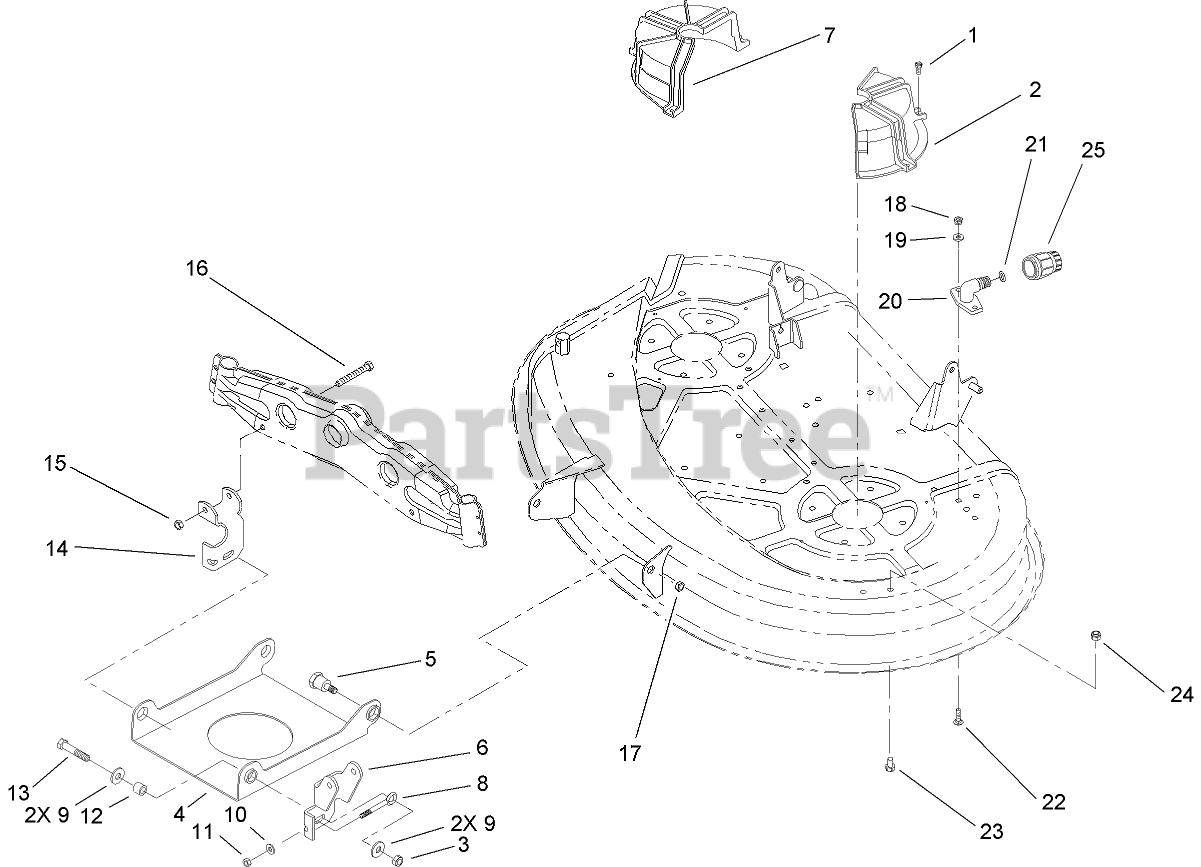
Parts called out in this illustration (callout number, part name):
1	SCREW-HWHTF
2	GUIDE-BELT, LH
3	NUT-LOCK, NI
4	PAN-DECK SUSPENSION, FRONT
5	BOLT-SHOULDER, HH
6	BRACKET-SUSPENSION, LH
7	GUIDE-BELT, RH
8	SCREW-ADJUSTING
9	WASHER-HARDENED
10	WASHER-FLAT
11	NUT-LOCK, NI
12	SPACER
13	SCREW-HH
14	BRACKET-SUSPENSION, RH
15	NUT-LOCK, NI
16	SCREW-HH
17	NUT-LOCK, NI
18	NUT-LOCK, NI
19	WASHER-FLAT
20	FITTING-WASHOUT
21	O-RING
22	BOLT-CARR
23	SCREW-HH
24	NUT-LOCK, NI
25	CONNECTOR-HOSE
